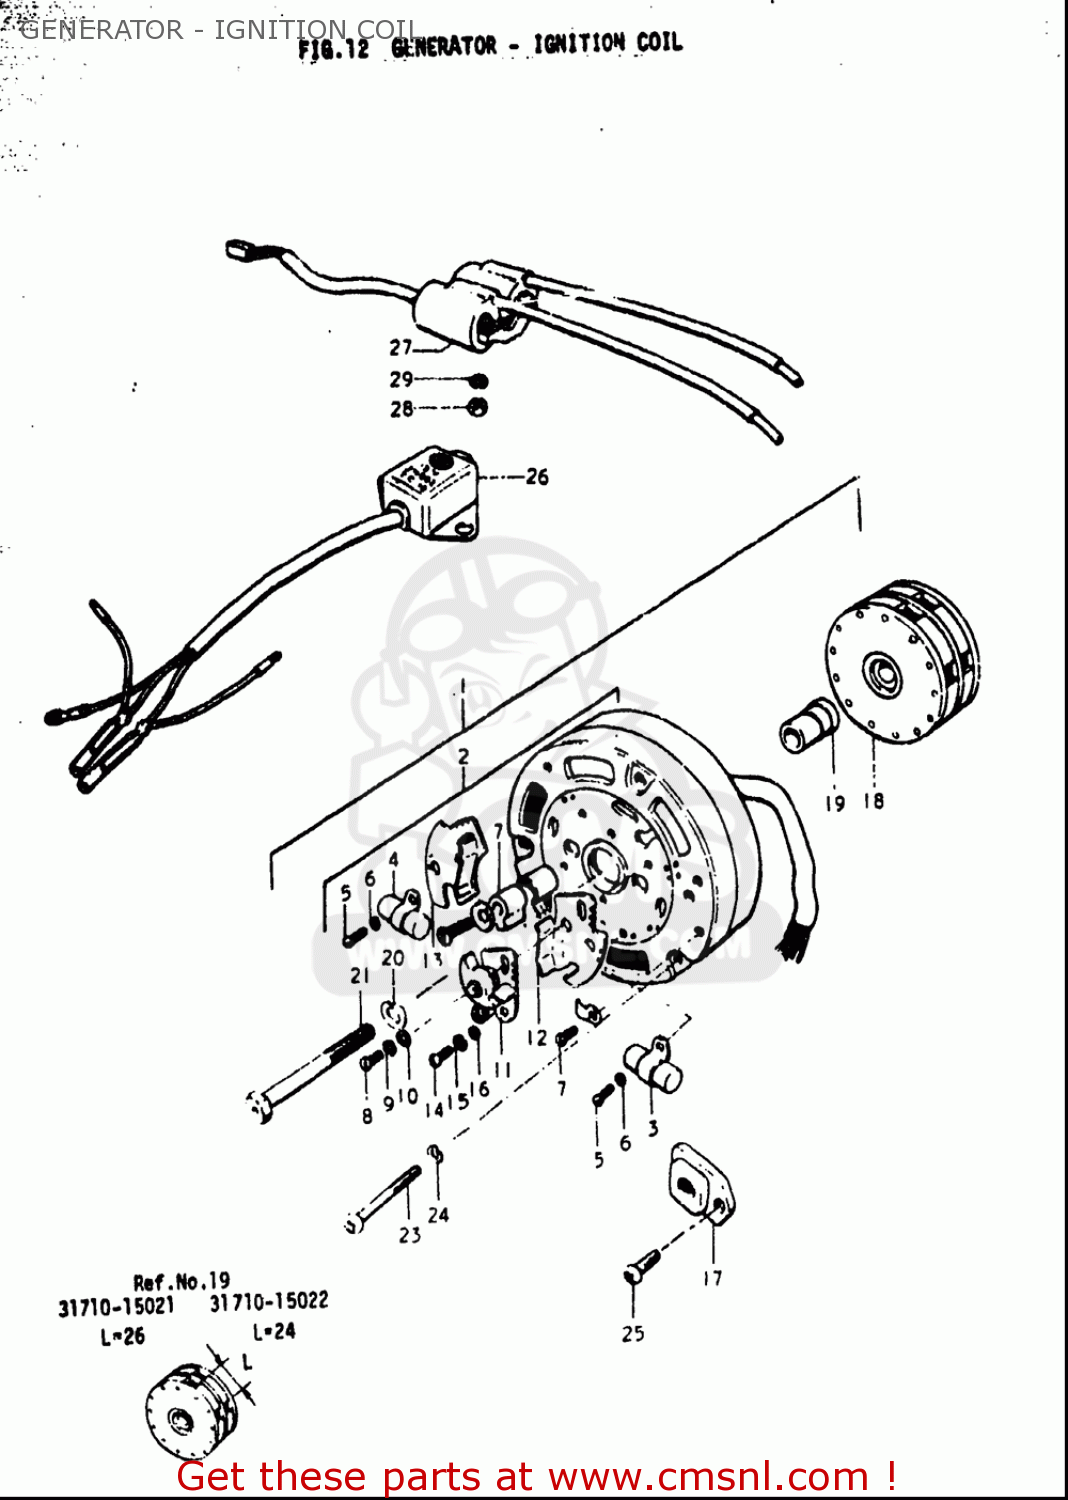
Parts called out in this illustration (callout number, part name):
3	CONDENSER,R
4	CONDENSER,L
5	SCREW 4X6
6	WASHER,LOCK
7	SCREW 4X6
8	SCREW(4X10)
9	WASHER,LOCK
10	WASHER
11	POINT ASSY,CONTACT
14	SCREW(4X10)
15	WASHER,LOCK
16	WASHER
20	WASHER,LOCK
23	SCREW
24	WASHER,LOCK
25	SCREW
27	COIL ASSY,IGNITION
28	NUT
29	WASHER,LOCK
